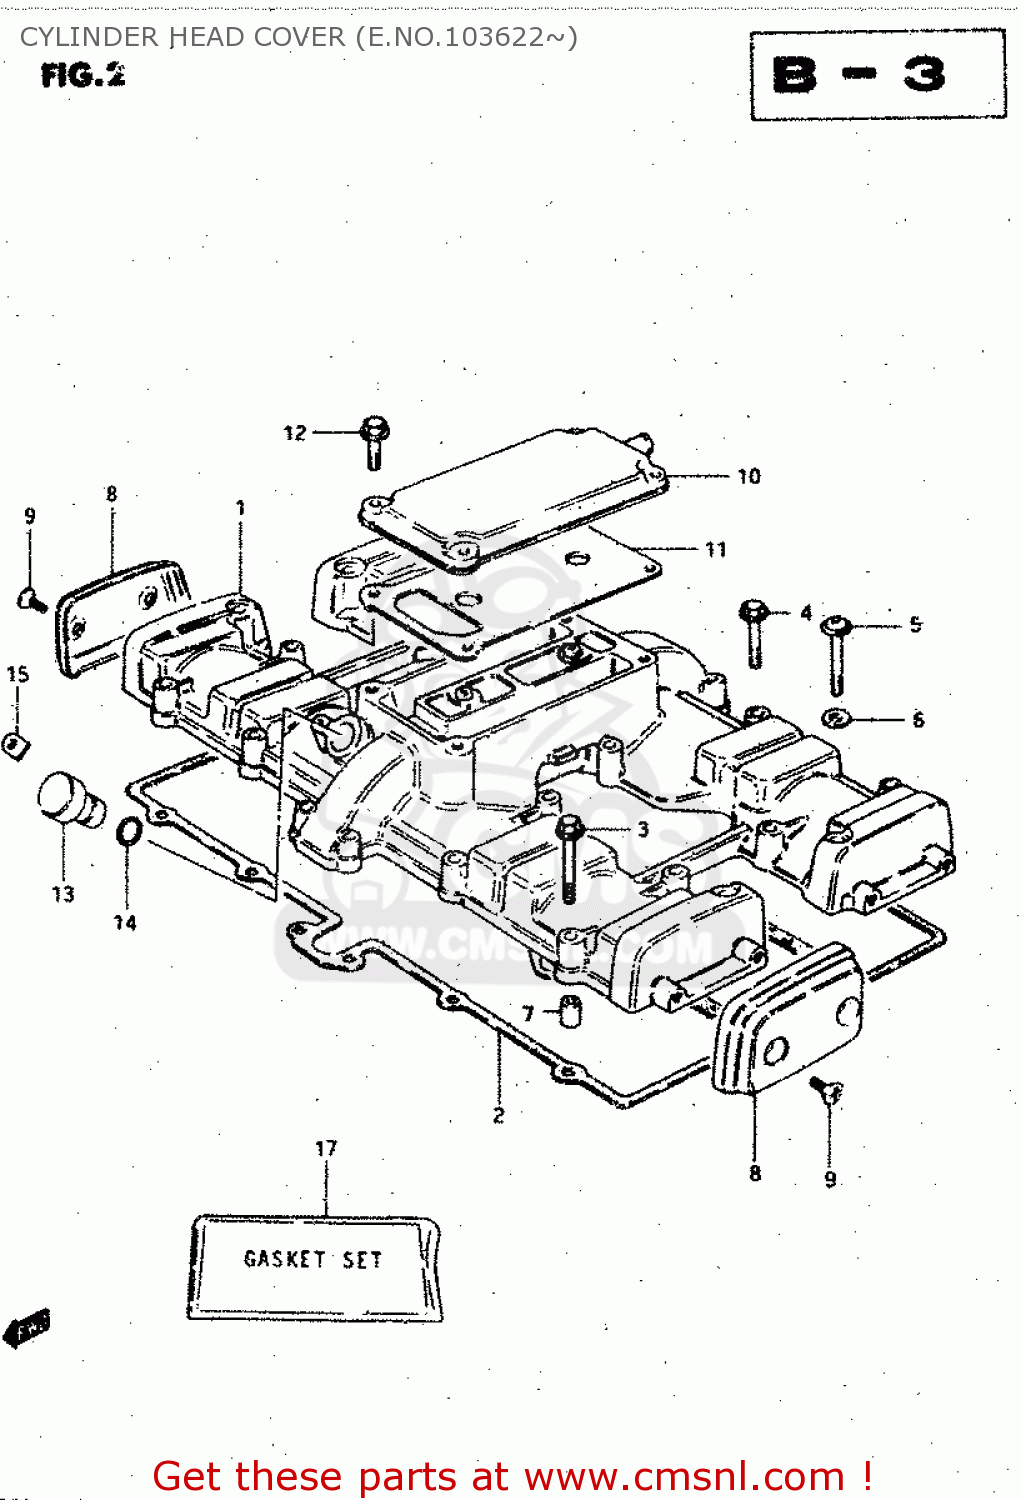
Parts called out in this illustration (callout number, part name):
1	COVER,CYLINDER HEAD
2	GASKET,CYLINDER HEAD COVER (MCA)
3	BOLT
4	BOLT 6X35
5	SCREW 6X40
6	WASHER
7	PIN(6.2X8X11)
8	CAP,CYLINDER HEAD COVER
9	SCREW(5X12)
10	COVER,BREATHER
11	GASKET (MCA)
12	BOLT,REAR
13	PLUG,TACH GEAR SLEEVE HOLE
14	SEAL,TACHOMETER DRIVEN
15	PLATE,TACH DRIVE GEAR SLEEVE
16	SCREW(5X12)
17	GASKET SET
